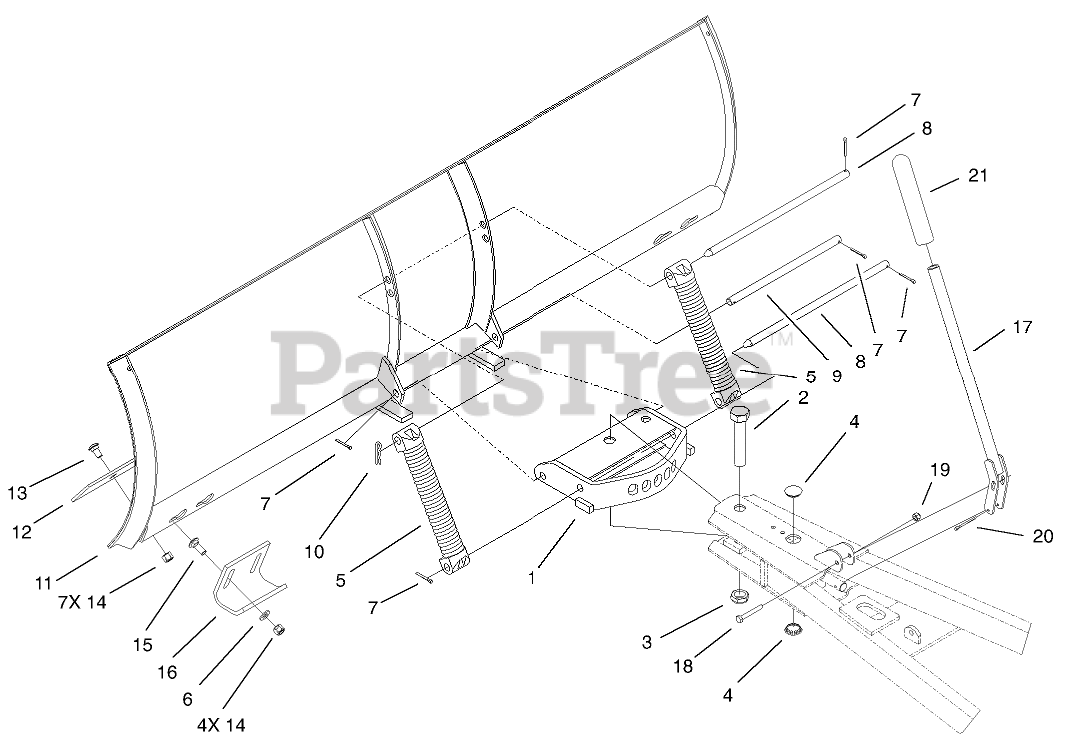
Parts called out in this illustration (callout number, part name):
1	QUADRANT
2	SCREW-HH
3	NUT-LOCK
4	PLUG
5	LUG / SPRING ASM
6	WASHER-FLAT
7	PIN-COTTER
8	ROD-PIVOT, BLADE
9	ROD-LOWER
10	PIN-HAIR
11	Blade-56 Inch
12	Plate-Blade Edge
13	SCREW-CARR
14	NUT-LOCK, NI
15	BOLT-CARR
17	LEVER-INDEX
18	SCREW-HH
19	NUT-LOCK, NI
20	PIN-COTTER
21	GRIP-HANDLE
